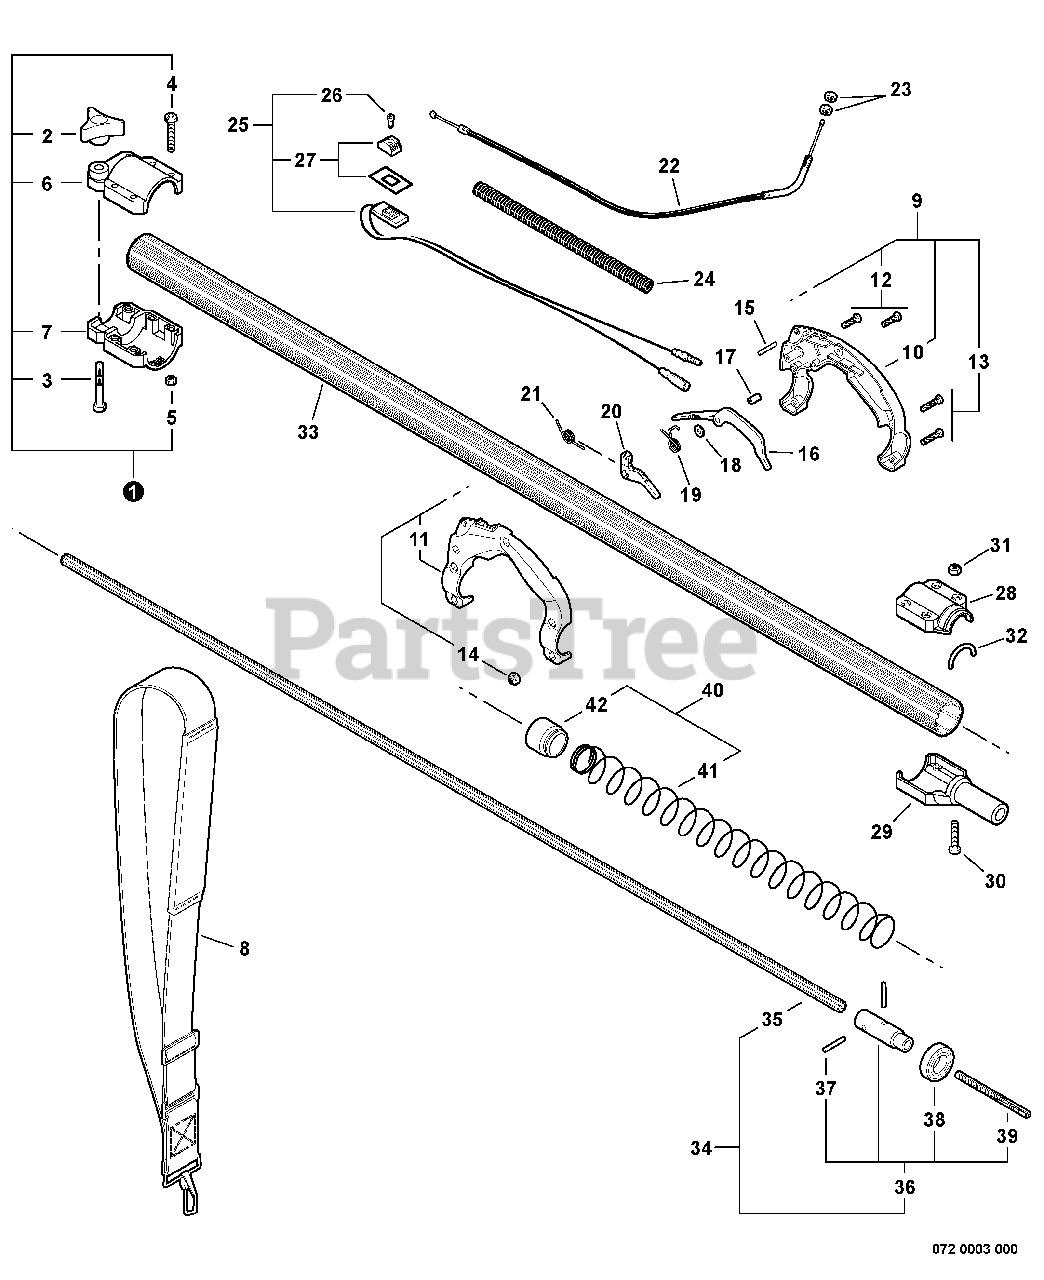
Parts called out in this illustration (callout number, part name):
1	COLLAR ASSY
2	THUMBSCREW
4	SCREW - 10-24 X 1-1/4"
5	LOCKNUT - 10-24
6	COLLAR, MAIN PIPE - UPPER
7	COLLAR, MAIN PIPE - LOWER
8	SHOULDER STRAP ASSY
9	HANDLE ASSY - REAR
10	HANDLE, REAR - LEFT
11	HANDLE, REAR - RIGHT
12	SCREW - 10-24 X 1-1/4"
14	LOCKNUT - 10-24
15	PIN - LOCATING
16	LOCKOUT, THROTTLE
17	COLLAR - 5
18	WASHER - 5
19	SPRING, LOCKOUT LEVER
20	TRIGGER, THROTTLE
21	SPRING, TRIGGER
22	CABLE, THROTTLE
24	TUBE, PROTECTIVE - CORRUGATED
25	IGNITION SWITCH ASSY
26	SCREW - 3X10
27	KNOB, SWITCH - ORANGE
28	CAP, LOWER SHAFT TUBE ADAPTER
29	ADAPTER, LOWER SHAFT TUBE
31	LOCKNUT - 10-24
33	PIPE, MAIN - ORANGE
34	DRIVESHAFT ASSY
35	DRIVESHAFT
36	SHAFT CONNECTOR KIT
38	BEARING, BALL - 6002
40	FLOATING BUSHING ASSY
42	BUSHING, FLOATING
